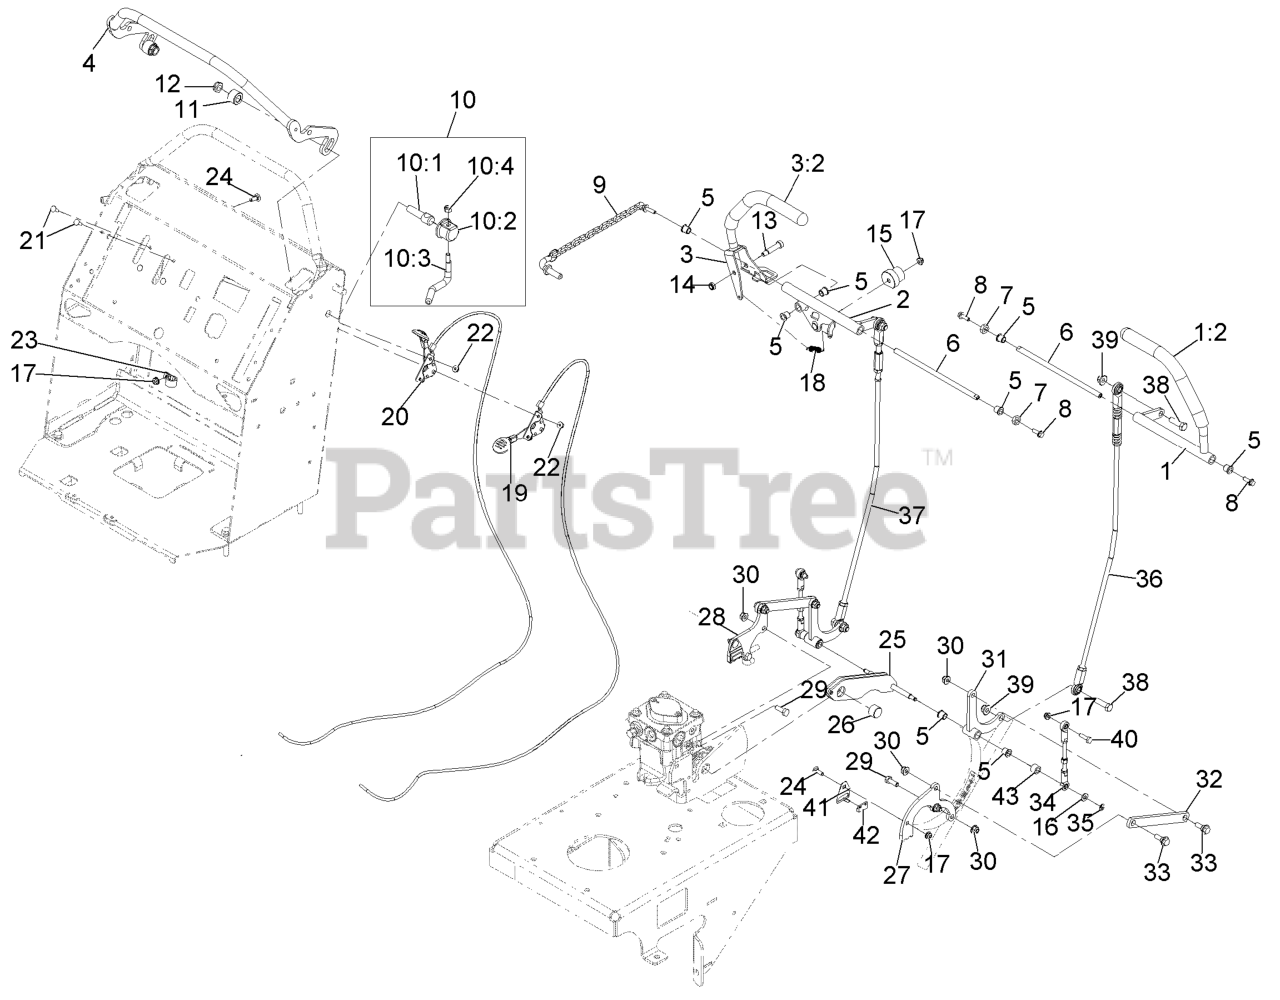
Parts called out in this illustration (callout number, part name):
1	LEVER ASM, LH
1:2	GRIP-HANDLE, CONTROL
2	WELD, MOTION CONTROL
3	ASM, LEVER W/ GRIP, RT
3:2	GRIP-HANDLE, CONTROL
4	TUBE ASM, FRONT SPEED CONTROL
5	BEARING
6	SHAFT-PIVOT, MOTION CONTR
7	SPACER-SHAFT, DRIVE LEVER
8	SCREW-HHF
9	HOC PIN ASM
10	LEVER ASM
10:1	SCREW-LOCK
10:2	CAP-LOCK
10:4	NUT-LOCK, NI
11	SPACER-CLAMP
12	NUT-HEX
13	SCREW-HSH
14	NUT-LOCK, NI
16	WASHER-FLAT
17	NUT-LOCK, NI
18	SPRING-EXTENSION
19	CONTROL-THROTTLE
20	CONTROL-CHOKE
21	BOLT-CARR
23	CLAMP-CABLE
24	BOLT-CARR
25	BELLCRANK LINK ASM
26	PIN-BELLCRANK LINK RETAIN
27	ARM-PUMP CONTROL
28	ARM, PUMP CONTROL RH
29	SCREW-HH
30	NUT-HF, NI
31	BELLCRANK-LOWER
32	LINK-BELLCRANK, PUMP
33	SCREW-SHOULDER
34	VERTICAL ADJUST LINK
36	LINKAGE-TRACKING CONTROL,
37	LINKAGE-TRACKING CONTROL,
38	SCREW-HH
39	NUT-HF, NI
40	SCREW-HH
41	CLAMP-SWITCH
42	ACTUATOR-SWITCH, REED
43	SPACER-WHEEL
